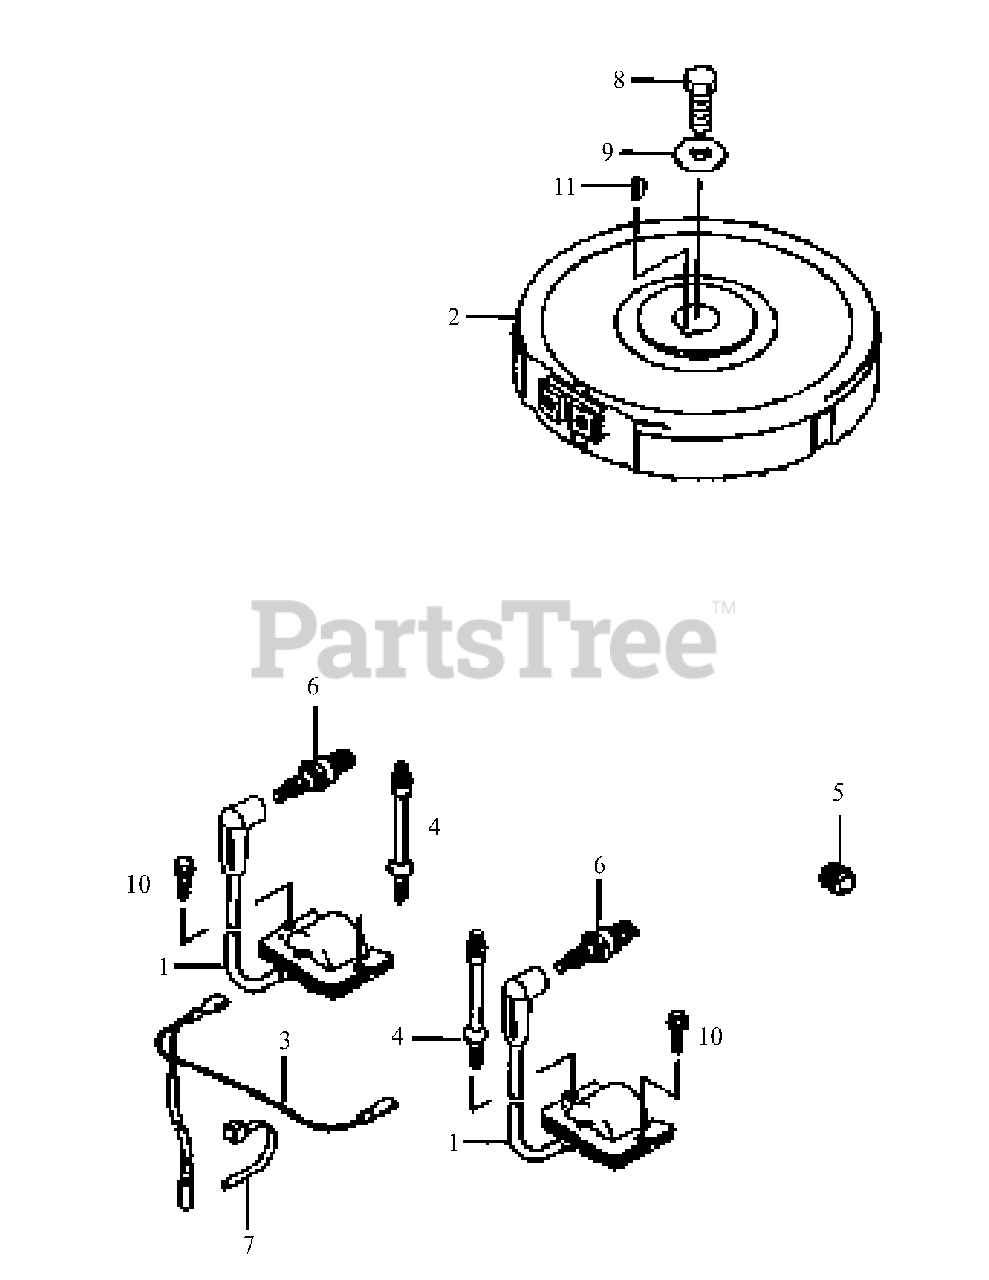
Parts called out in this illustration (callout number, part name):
1	Coil, Ignition
2	Flywheel
4	Stud
6	Spark Plug
10	Bolt, Flange
11	Key, Woodruff
